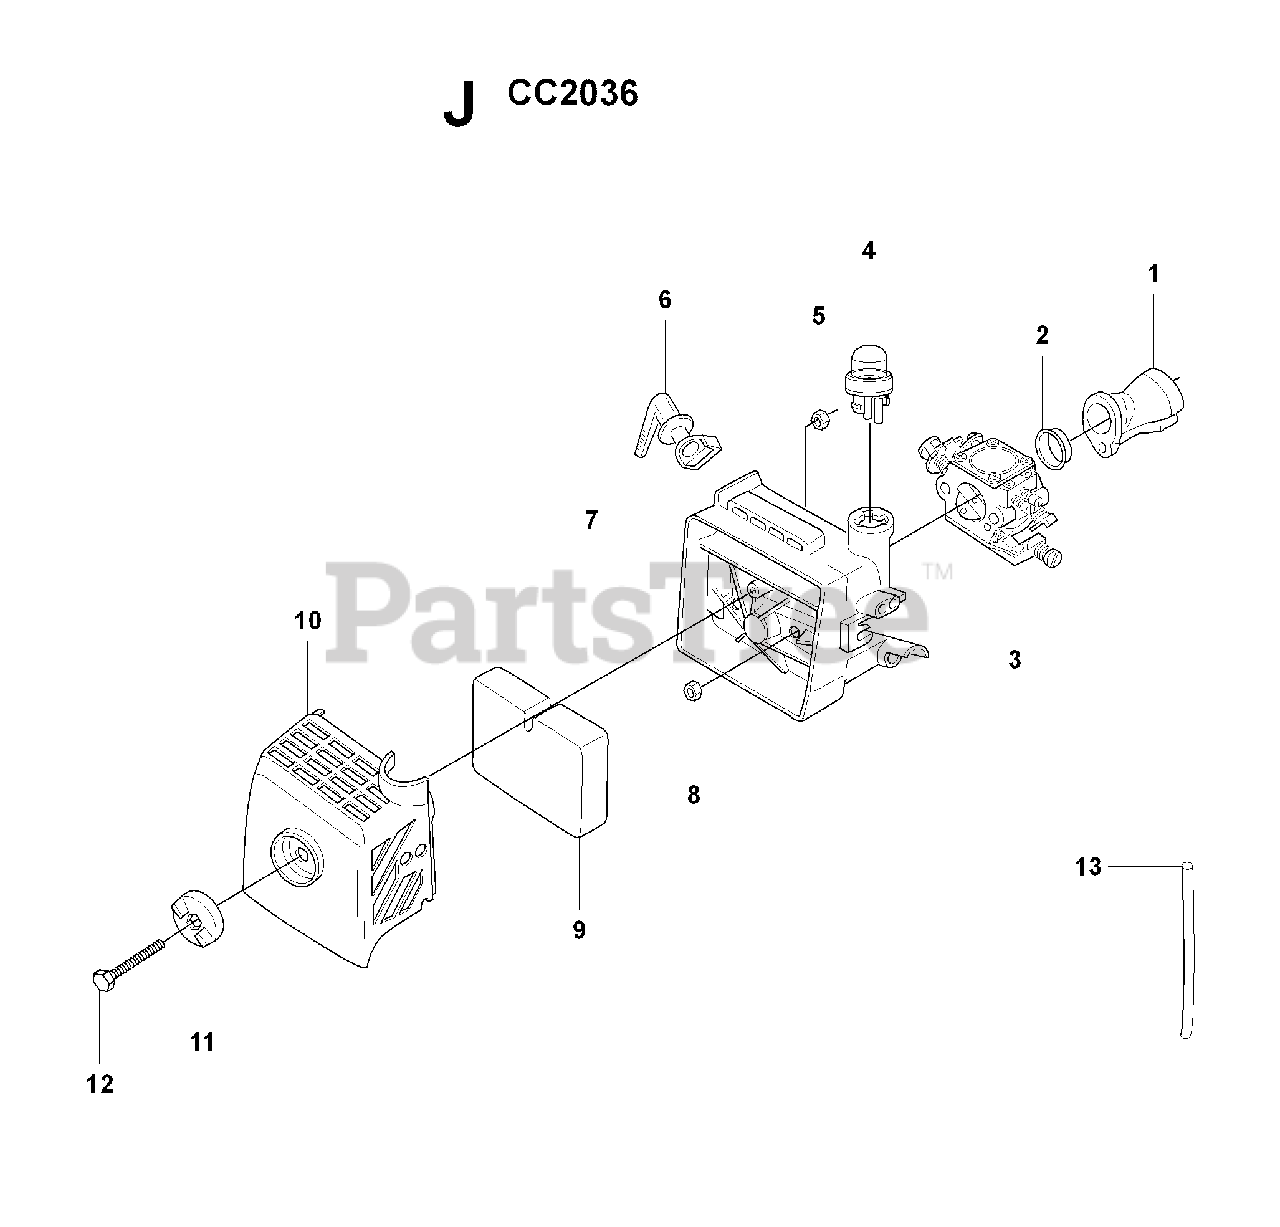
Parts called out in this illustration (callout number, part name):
1	INDUCTION PIPE
3	%CARBURETOR WT548 WALBRO
4	AIR PURGE BUBBLE
6	CHOKE CONTROL
7	FILTER HOLDER
9	AIR FILTER
12	SCREW 25MM THREAD LENGTH
13	FUEL HOSE/38MM
